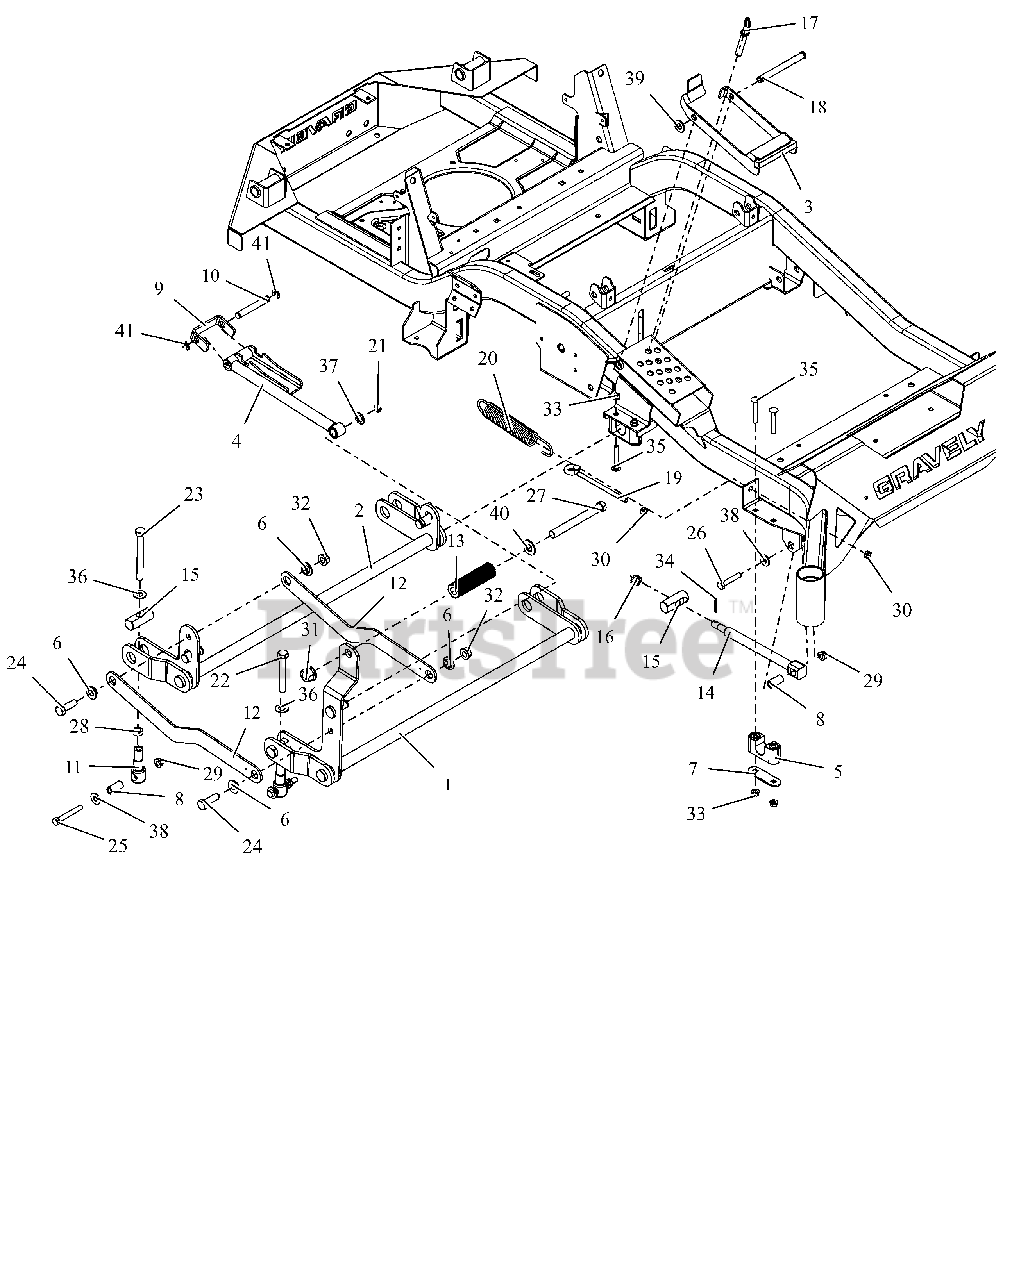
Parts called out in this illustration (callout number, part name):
1	WLDMT, FRONT DECK LIFT PIVOT
2	WLDMT, REAR DECK LIFT PIVOT
3	BRKT, HOC TRANSFER LOCK
4	WLDMT, HOC ARM
5	ASM-BUSHING, DECK LIFT
6	BSHG-FLG .515X.750X.310X1.120
7	PLATE, BEARING SUPPORT
8	SPACER, DECK LEVELING
9	BRKT, HOC LINE
10	ROD, HOC PIVOT
11	LINK, DECK LIFT FORMED
12	LINK, DECK LIFT
13	ROD, FOOT PEDAL (BLACK)
14	DRAG,LINK-HD
15	PIN, DECK LIFT
16	NUT-SL .50-13
17	PIN, .50 X 2.20 USABLE LG BALL
18	PIN, SLIC-.500X4.97X4.55 -ZC
19	BOLT,.38-16 X 5.25-.62 DIA EYE
20	SG-TENS .162X1.25X8.25 WLD 25
21	RG-RTNG-EXT .625X.050
22	BLT, HEX 0.5-13X3.5F GR5 ZCC
23	BLT, HEX .50-13X4.50F G8 ZCC
24	BLT,HEX .50-13X1.50 G5 ZCC
25	BLT, HEX .38-16X2.75 G8 ZCC
26	BLT,HEX .38-16X2.00 G5 ZCC
27	BLT, HEX .62-11X5.50 G5 FBP
28	NUT-JAM .500-13 G2 ZCC
29	NUT-LK-TOP-FLG .38-16 ZC120
30	NUT-JAM .375-16 G2 ZCC
31	NUT,FLG-TOP LK .625-11 FBP
32	NUT-LK-TOP-FLG .500-13 GF ZCC
33	NUT,LK-CTR-FLG .31-18 GF ZCC
34	PIN,CTR.12X1.25EXTPRSQCT ZC120
35	BLT, RHSSN.31-18X2.25 G5 ZCC
36	WSHR, FLT .557X1.040X.102 ZCC
37	WSHR, FLT .630X1.005X.062 ZCC
38	WSHR,FLT .438X1.00X.083 ZCC
39	WSHR,FLT .531X1.062X.095 ZCC
40	WSHRFLT 5/8SAE CARBHARD FBP
41	RG-RTNG-EXT .500X.042 (E)
